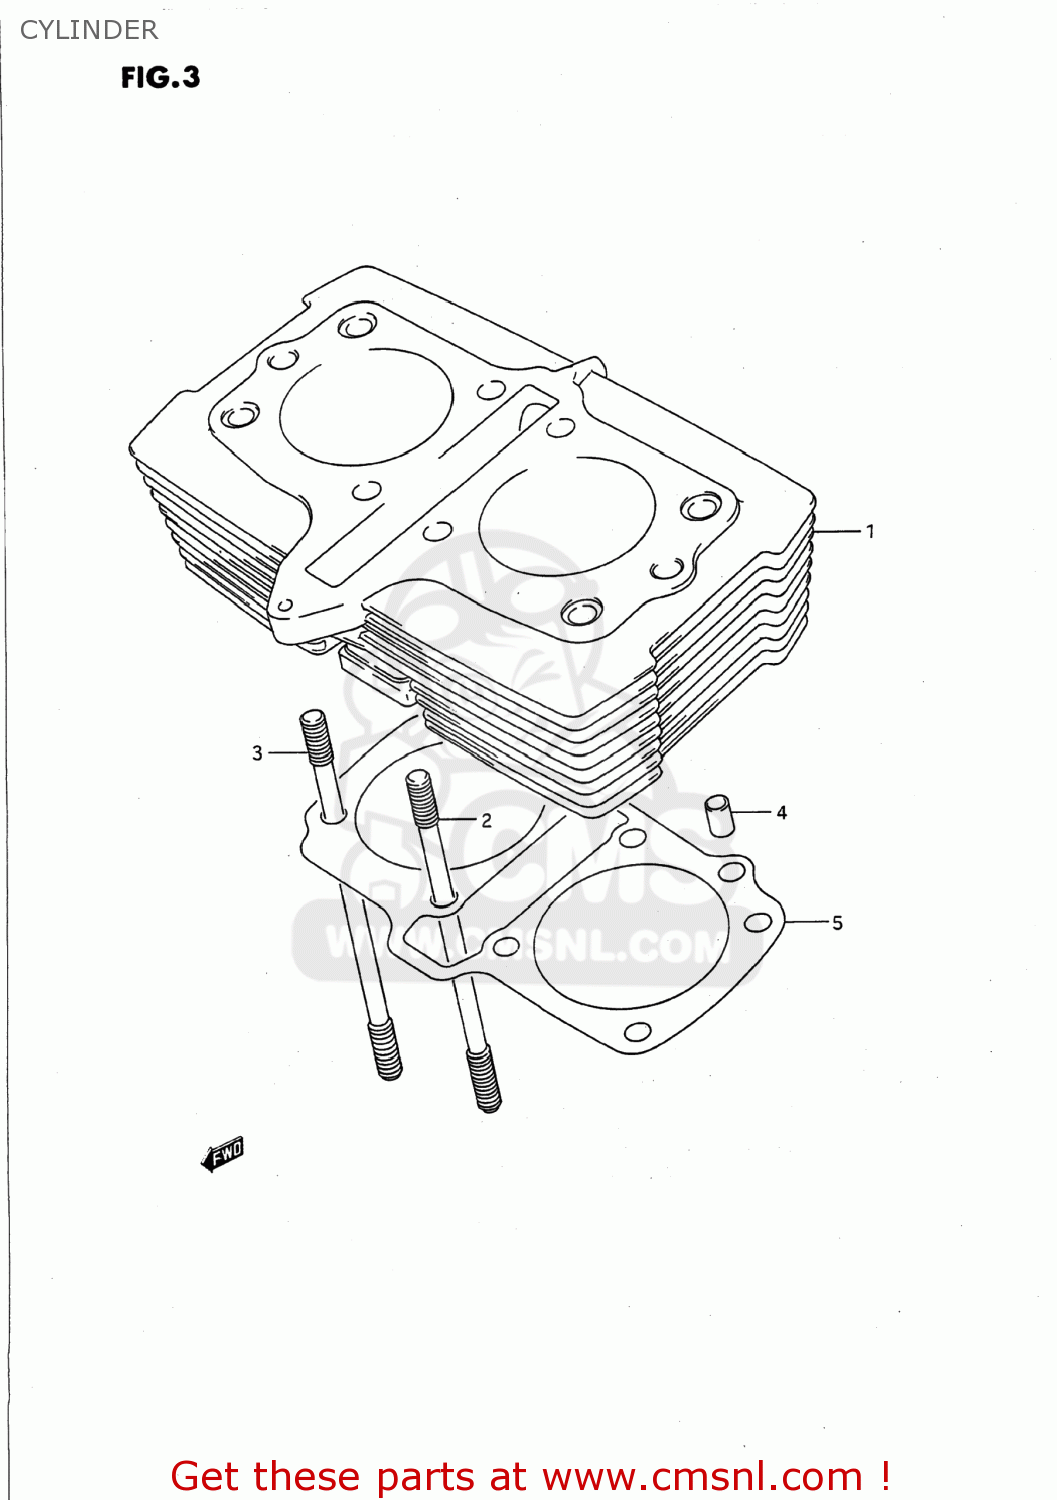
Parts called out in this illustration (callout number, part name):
1	CYLINDER
2	BOLT,STUD
3	STUD
4	PIN
5	GASKET,CYLINDER (NAS)
